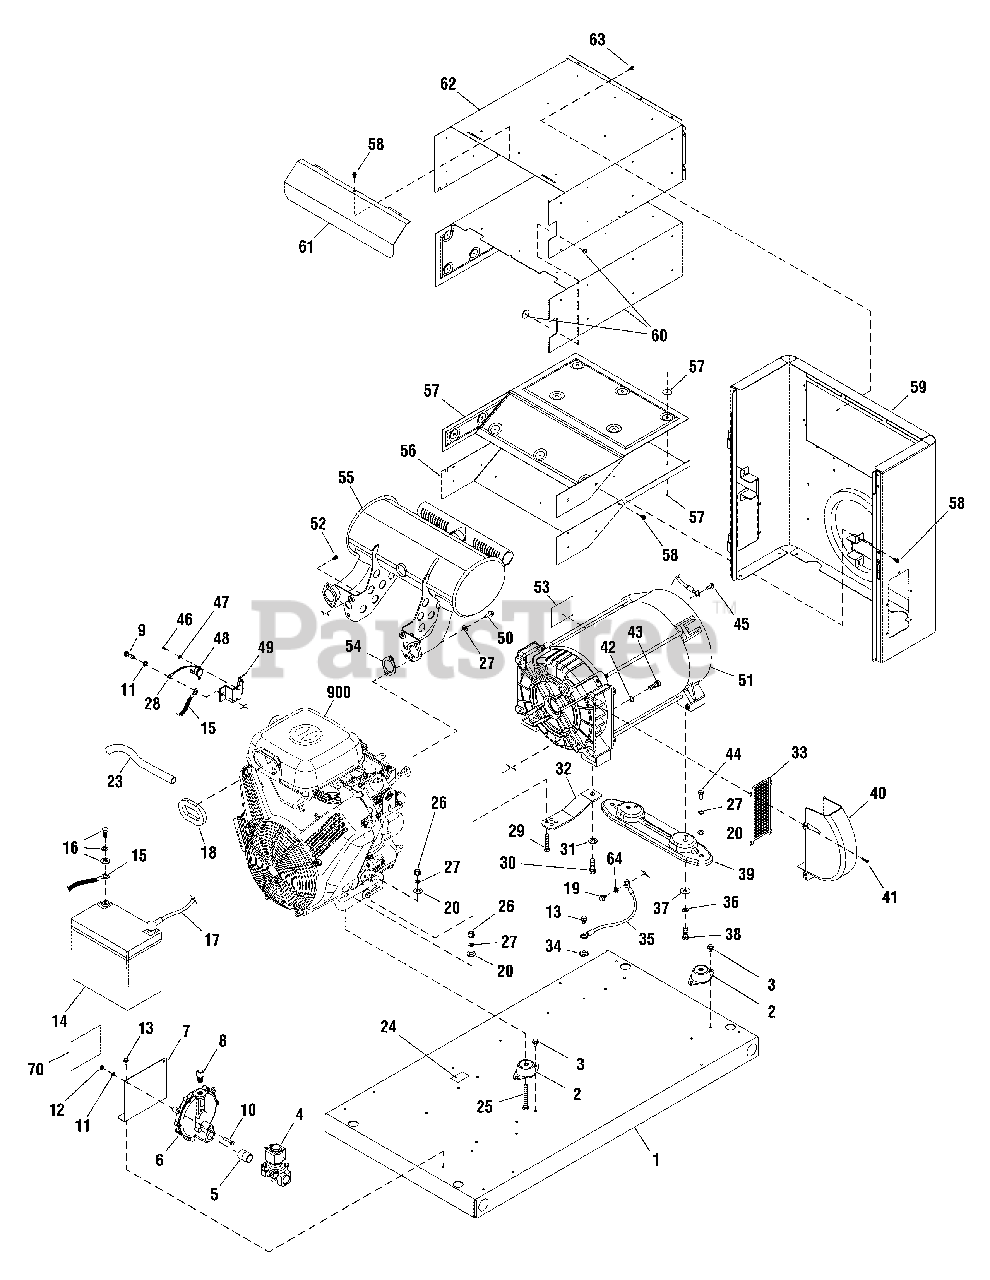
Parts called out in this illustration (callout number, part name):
2	MOUNT-VIBRATION
4	SOLENOID-GAS FUEL
6	REGULATOR-NG/LPG
7	BRACKET
9	* CAPSCREW, Hex Head, M6-1.0 x 16
10	* CAPSCREW, Hex Head, M6-1.0 x 30
11	* WASHER, Lock, 1/4
12	* NUT, M6-1.0
13	BOLT
16	KIT-HARDWARE BATTERY
18	TUBE
20	* WASHER, Flat, 5/16 (M8)
24	DECAL-OIL DRAIN
25	* CAPSCREW, Hex Head, 5/16-18 x 2.5
26	* NUT, 5/16-18
27	* WASHER, Lock 5/16 (M8)
29	* CAPSCREW, Hex Head, 5/16-18 x 2
30	* CAPSCREW, Hex Head, M12-1.75 x 35
31	* WASHER, M12
34	* WASHER, Shakeproof, M6-1/4
36	* WASHER, Lock, 3/8
37	* WASHER, Flat, 3/8
38	* CAPSCREW, Hex Head, 3/8-16 x 1
39	SUPPORT-ALTERNATOR
41	* SCREW, Taptite, M5.8 x 10
42	* WASHER, Lock, 3/8
43	* CAPSCREW, Socket Head, 3/8-16 x 1-1/4
44	* CAPSCREW, Hex Head, 5/16-18 x 3/4
45	BOLT
46	* PPHMS-4-40 x 0.19
47	* WASHER, Lock, #4
49	PLATE-TEMP SWITCH
50	SCREW
51	ALTERNATOR
53	DECAL
59	BULKHEAD-ALTERNATOR
62	BOX-MUFFLER TOP
64	* WASHER, Shakeproof, M6
900	** ENGINE
